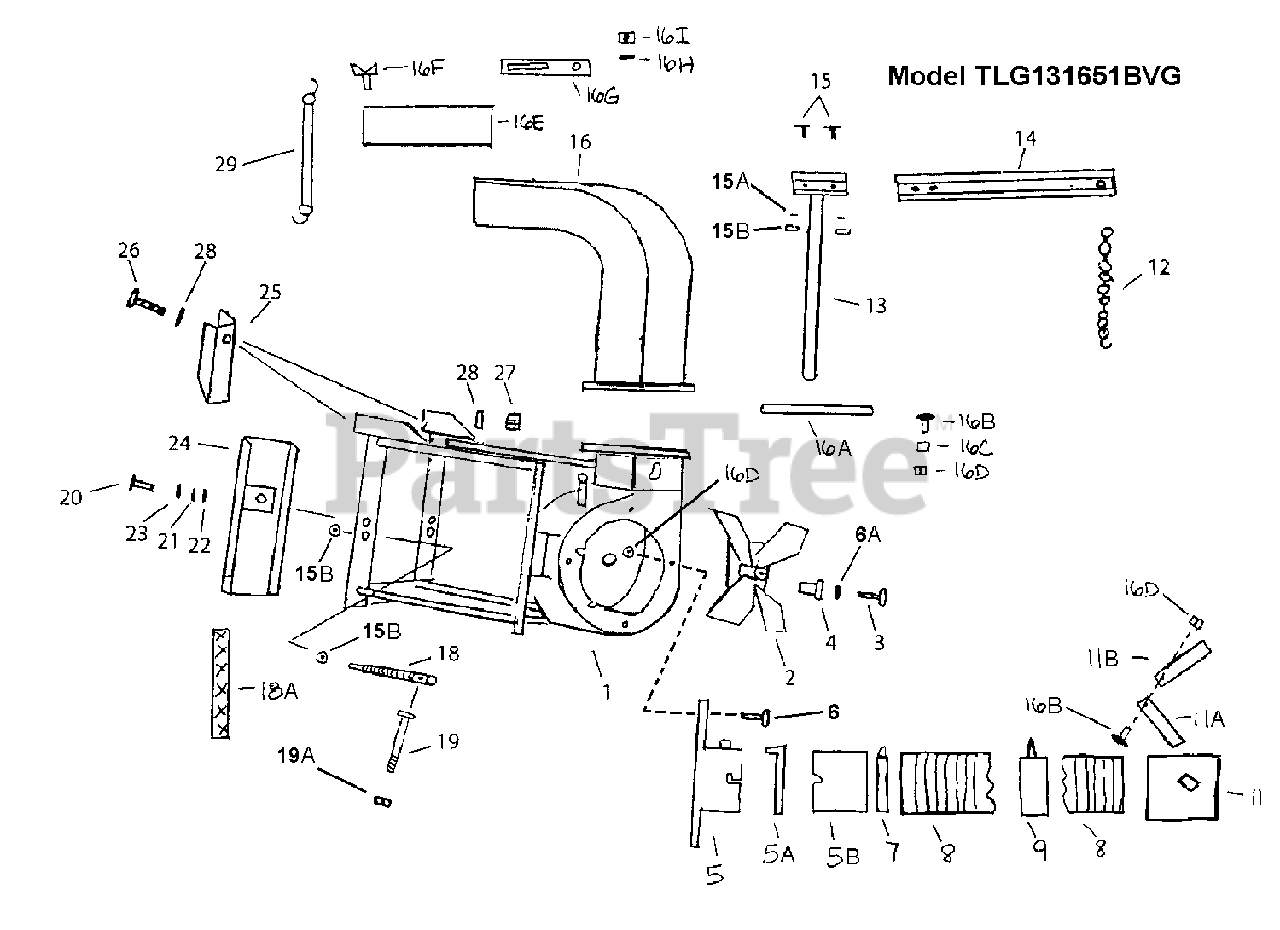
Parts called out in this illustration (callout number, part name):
1	Motor Base & Housing Swivel Style for 13hp BVG
2	Impeller, 16.5" (Complete w/Hub & Hardware - Includes Ref. 3 & 4)
3	5/16-18 x 1-1/4 GR5 Hex Bolt
4	Taper-Lok Hub 1in Diameter
5	Intake Flange
5A	Intake Flange Safety Cover 8"
5B	Quick-Release Hose Adapter 8"
6	5/16 x 3/4 Thread Bolt
7	8in Hose Clamp
8	Intake Hose 8.00 x 10ft
9	Hose Support Band
11	Intake Nozzle 8in
11A	Intake Nozzle Adjustable Handle
11B	Intake Nozzle Handle Grip
12	Boom Chain
13	Lower Boom Support
14	Upper Boom Support
15	1/2-13 x 1 Hex Bolt
15A	1/2 Lock Washer
15B	1/2-13 Nut
16	Exhaust Elbow & Stack
16A	Elbow Retaining Ring
16B	5/16-18 x 1" Hex Bolt
16C	5/16 Pivot Spacers
16D	5/16 Lock Nuts
16E	Stack Extension
16F	3/8 Wing Bolt
16G	Stack Extension Retainer
16H	3/8 Lock Washer
16I	3/8 Wing Nut
18	Pusher Rod 1 x 7
18A	Rubber Gasket
19	3/8-16 x 5 Hex Bolt (Pusher Rod Handle)
20	3/8 x 3/4 Hex Bolt
21	3/8 Flat Washer
22	1/2 Flat Washer
23	3/8 Lock Washer
24	Front Pusher Plate
25	Rear Holder Arm
26	5/8 x 4 Hex Bolt
27	5/8 Lock Nut
28	5/8 Flat Washer
29	Rubber Tie Down
